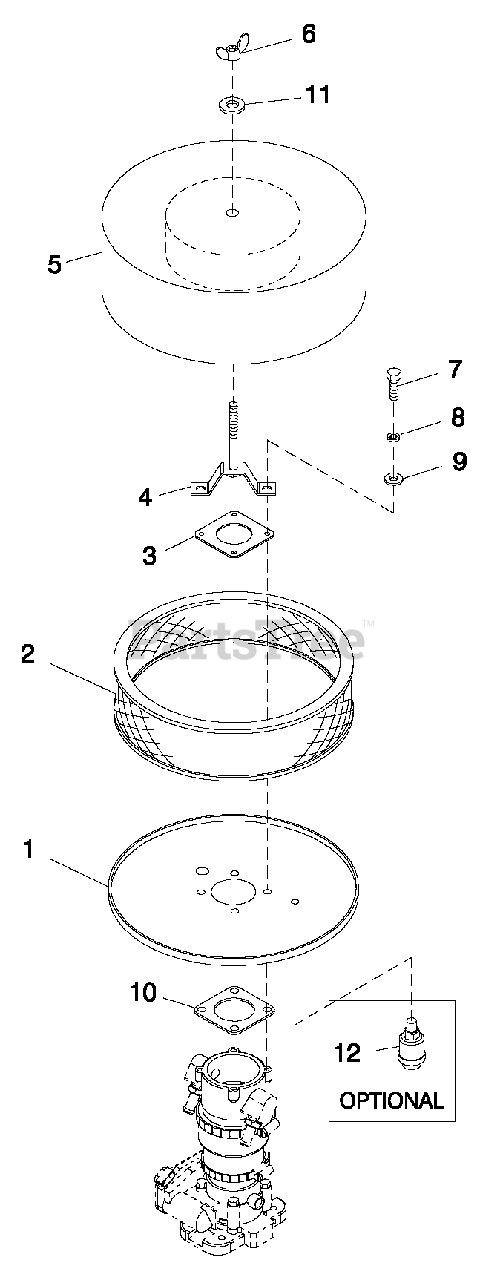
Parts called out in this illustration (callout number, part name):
1	AIR CLNR BTM PLT W/CPLR 8.1L
2	ELEMENT AIR FILTER
3	TOP PLATE VENTURI
4	HOLD DOWN AIR CLEANER PLATED
5	PLATE AIR CLEAN TOP 5.4L/6.8L
6	NUT WING 1/4-20 NYLK
7	SCREW HHC M6-1.0X 16 G 8.8
8	WASHER LOCK M6-1/4
9	WASHER FLAT M6
10	GASKET MIXER BODY
11	WASHER FLAT 1/4-M6 ZINC
12	INDICATOR FILTER MINDER
